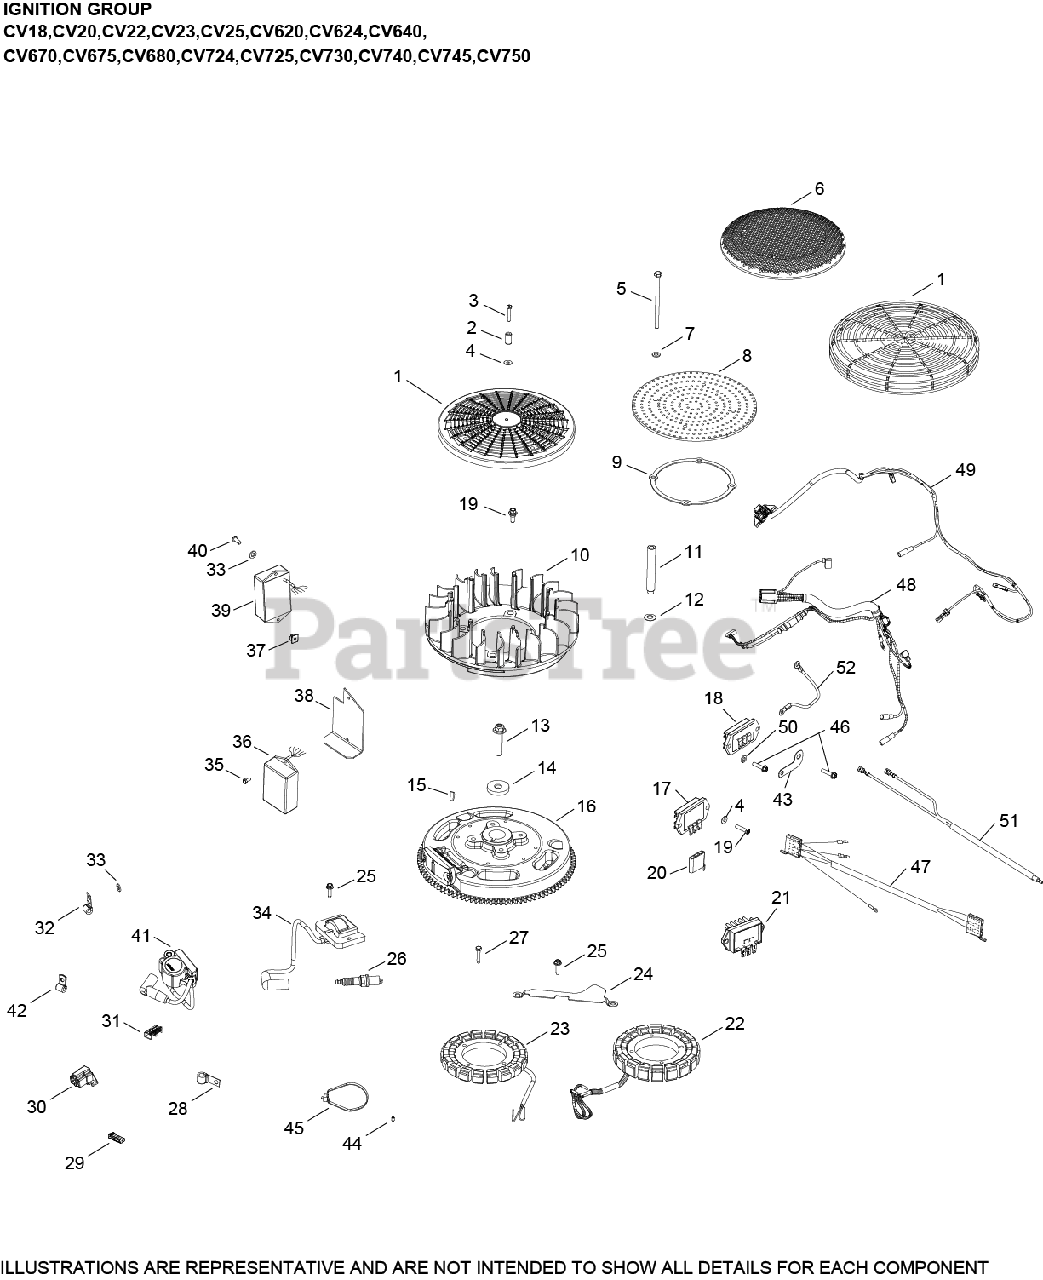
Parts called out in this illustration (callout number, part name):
1	KIT, GRASS SCREEN
3	SCREW, SLT HD CAP M4X0.7X25
13	SCREW, FLG M10X1.5X45 - (#25086361S)
14	WASHER, FLAT 13/32"
15	KEY, 3/16" X 5/8"
18	REGULATOR/RECTIFIER
20	CONNECTOR
23	KIT, 15 / 20 AMP STATOR
25	SCREW, THREAD FORMING
25	SCREW, THREAD FORMING - USE 25 086 473-S
26	PLUG, SPARK (STD)
27	SCREW, THREAD FORMING
28	CLIP, CABLE
30	CONNECTOR
34	KIT, MODULE IGNTN (CDI FIXED)
49	HARNESS, WIRING ASSEMBLY
50	WASHER, LOCK
51	LEAD, DUPLEX
